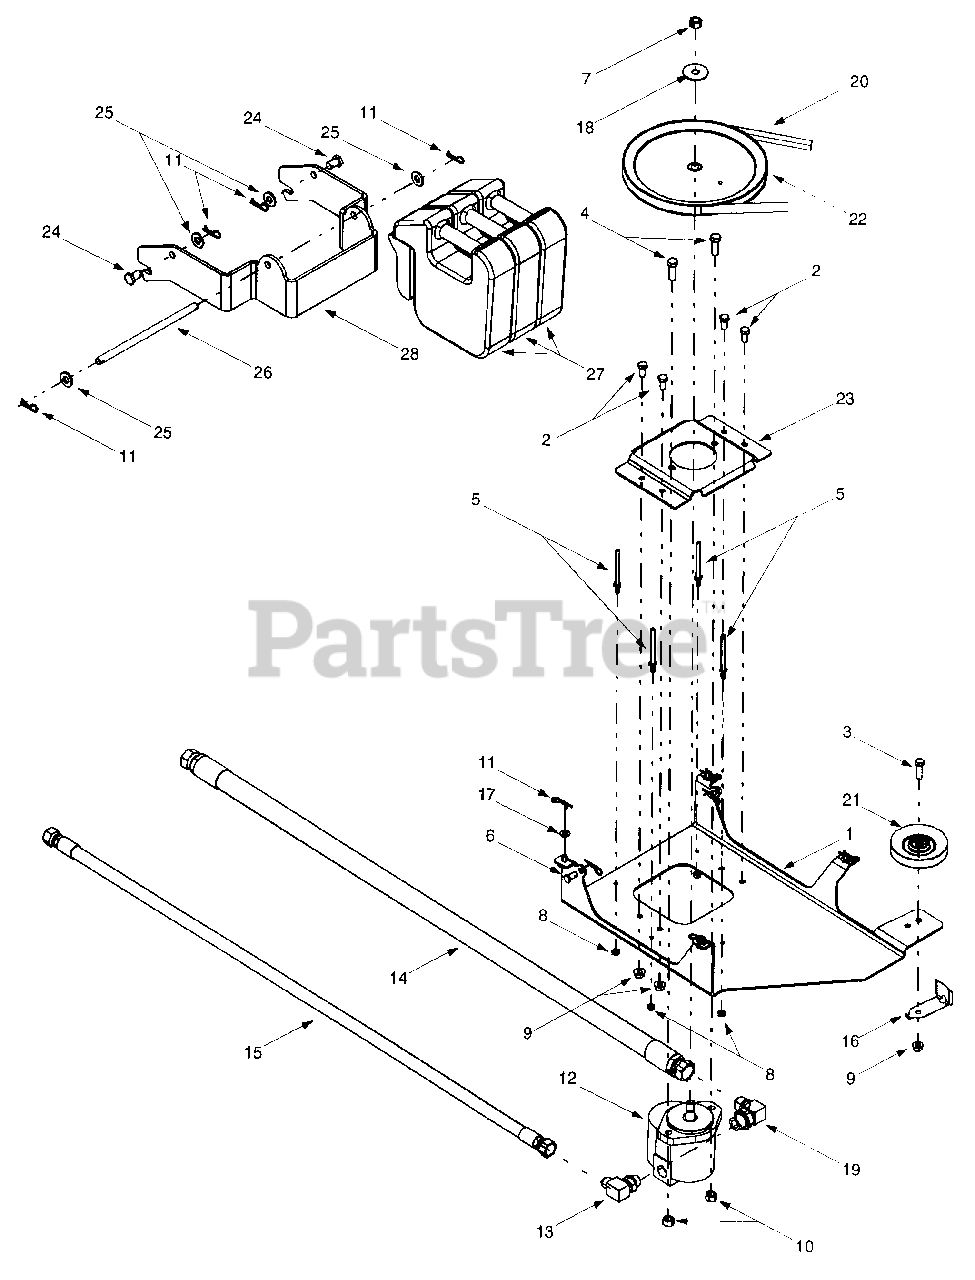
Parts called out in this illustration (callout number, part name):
3	Hex Cap Screw, 3/8-16 x 1.25
4	Hex Cap Screw, 7/16-20 x 1.25
5	Belt Keeper Pin
6	Clevis Pin, 3/8 x .75
7	Hex Lock Nut, 1/2-20
8	Hex Lock Nut, 1/4-20
9	Hex Lock Nut, 3/8-16
10	Hex Lock Nut, 7/16-20
11	Click Pin, .092 x 1.64
12	Eaton Hydraulic Pump
13	90° Hydraulic Adapter, 7/8
14	Hydraulic Hose, 1.0625-12 x 54
15	Hydraulic Hose, .875-14 x 49
16	Belt Guard
17	Flat Washer, .344 x.688 x.065
18	Flat Washer, .531 x 1.75 x .090
19	90° Hydraulic Adapter, 1-1/16
20	V-belt
21	Idler Pulley, 5/8 x 4.0
22	Drive Pulley, 10.0
23	Pump Mounting Bracket
24	Clevis Pin, .5 x .78
25	Flat Washer, .531 x 1.062 x .134
26	Weight Guard Rod
27	45 lb. Suitcase Weight
